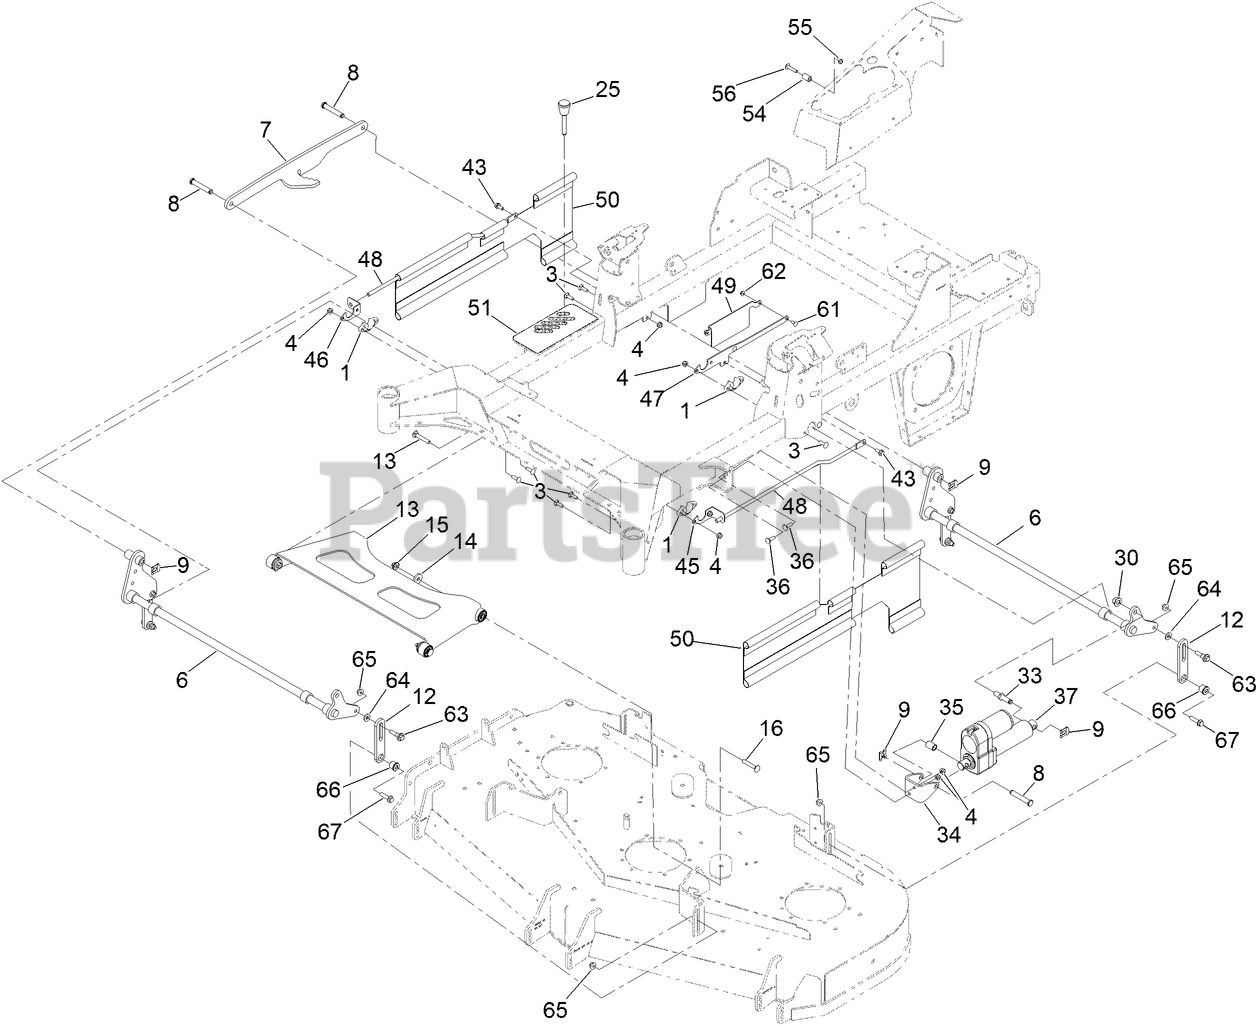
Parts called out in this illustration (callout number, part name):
1	BEARING-FLANGE
3	SCREW-CARR
4	NUT-HF, NI
6	DECK LIFT SHAFT ASM [BLACK]
7	LINK-LIFT
8	PIN-CLEVIS
9	CLIP-PIN
12	LINK-LIFT, DECK
13	ASM-DECK STRUT W/ BUSHINGS
14	WASHER
15	NUT-FLANGE, NI
16	SCREW-CARR
25	PIN-HOC
30	NUT-LOCK
33	PIN-PIVOT, ACTUATOR
34	CYL MOUNT PLATE
35	SPACER-ALUMINUM
36	BOLT-CARR
37	ACTUATOR-LINEAR
43	SCREW-HHF
45	BRACKET-MOUNT, UPPER FRONT (LH)
46	BRACKET-MOUNT, UPPER FRONT (RH)
47	BRACKET-MOUNTING, UPPER
48	ROD-SUPPORT, UPPER
49	BRACKET-FLAG
50	GUARD-SIDE
51	DECAL-HOC, MM
54	SPACER
55	NUT-LOCK, NI
56	SCREW-TORX
61	SCREW-CARR
62	NUT-HF
63	BOLT-SHOULDER
64	SPACER
65	NUT-HF, NI
66	BUSHING-DECK LIFT
67	SCREW-HHF
